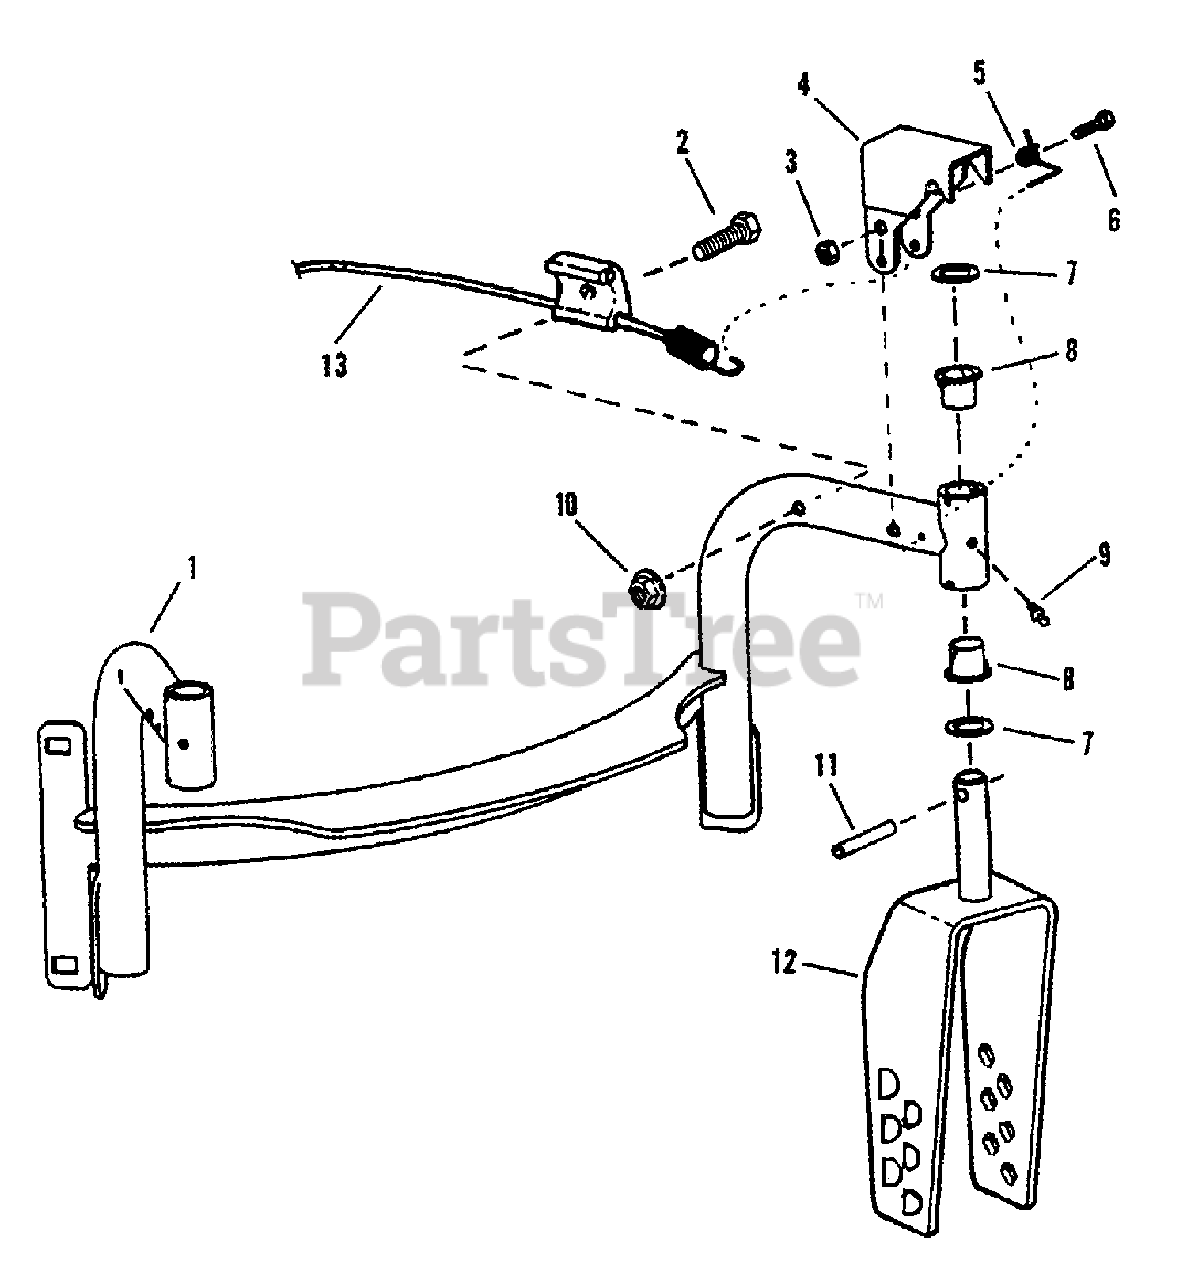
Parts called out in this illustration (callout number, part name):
1	WELDMENT, Front Bracket
2	SCREW, 1/4-20 x 1-1/2" Hex Cap
3	NUT, 1/4-20 Hex Lock
4	BRACKET, Swivel Lock
5	SPRING, Torsion
6	BOLT, 1/4-20 x 2" Hex
7	WASHER, 41/64" Flat
8	BUSHING, 5/8" Nylon
9	LUBE FITTING, Straight (press-fit for .187 dia. Hole)
10	NUT, 1/4-20 Hex Lock
11	PIN, 1/4 x 1-3/4" Roll
12	WELDMENT, L.H. Swivel Bracket
13	CONTROL, Swivel Wheel Lock Cable 56.5"
